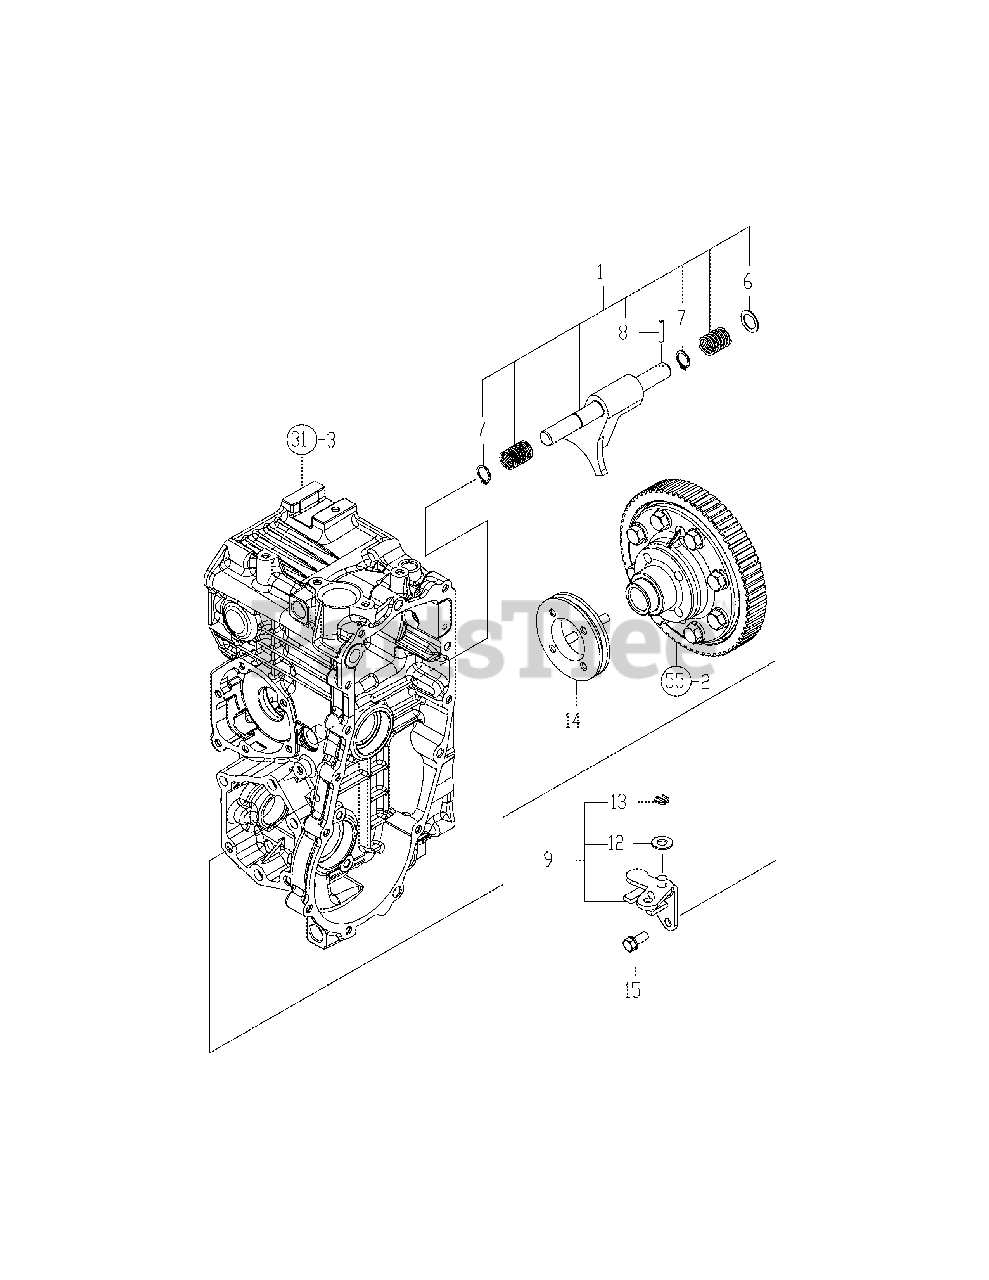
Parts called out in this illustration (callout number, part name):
1	Fork Kit, Diff.Lock
6	Spacer, 16.5X24X1
8	Pin, 4.0A X 25
9	Fulcrum Kit, Diff.
14	Slider, Diff.Lock
